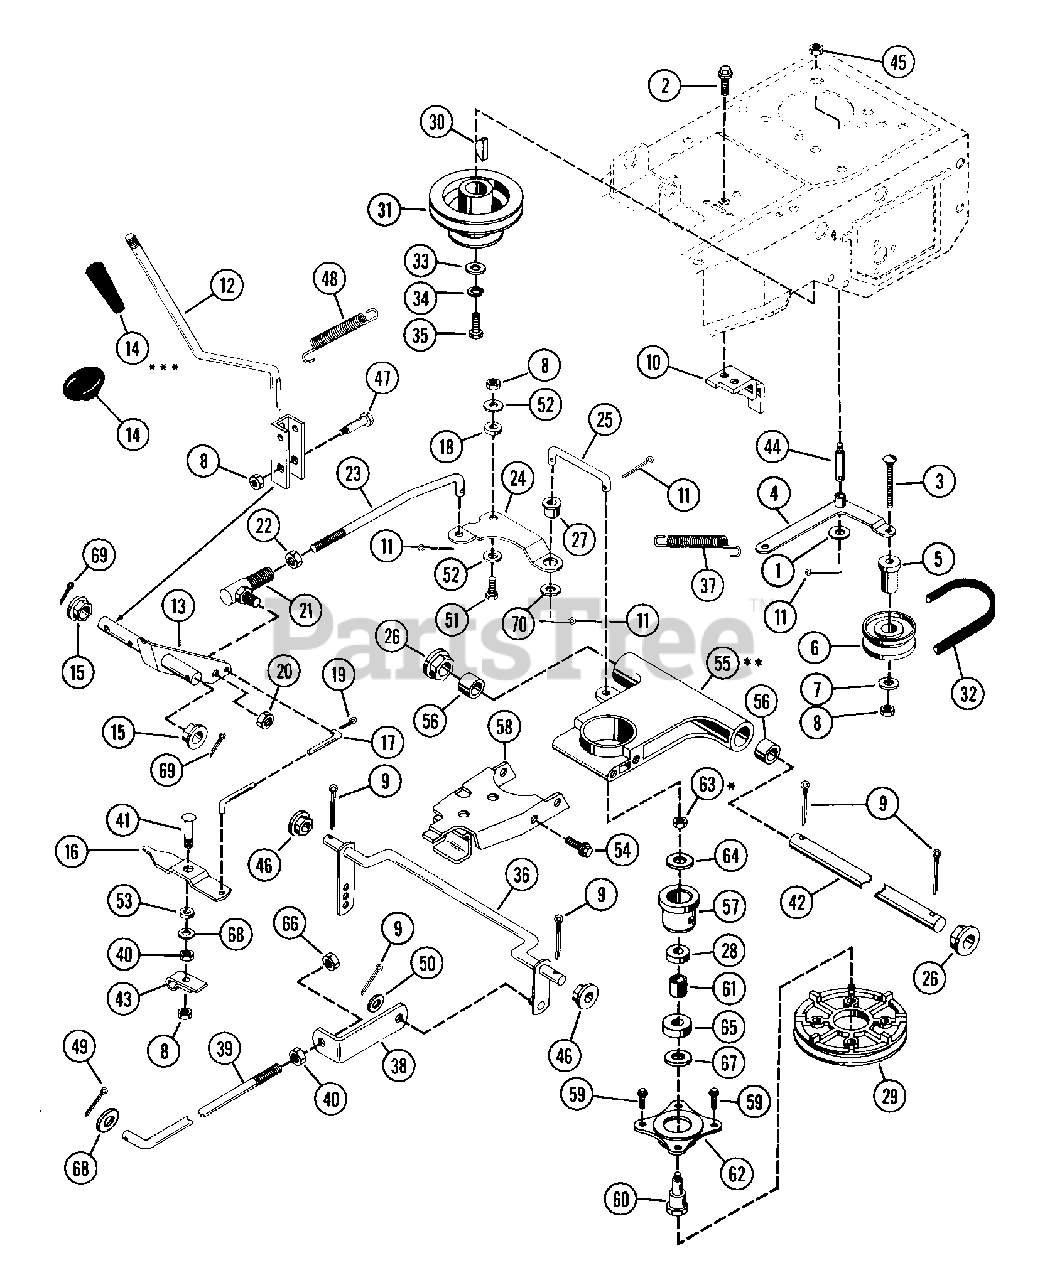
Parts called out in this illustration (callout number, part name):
1	WSHR-FL-STL .505X.880X.072 PL
2	BLT-SERHFWH .31-18X.50 PL
3	BLT-RDHDSQNK .31-18X1.25 SHTPL
4	IDLER ARM
5	SPACER -SHLD .344X.500X.469
6	IDLER
7	WSHR-FL-STL .38X.875X.083 PL
8	NUT-LK .312-18 GR A PL
9	PIN-COTR .12X1.0 PL
10	NEUTRAL STOP
11	PIN-COTR .09X.75 PL
12	SHIFT LEVER
13	SHIFT ARM
14	SHIFT BALL
14	GRIP
15	FLANGE BUSHING
16	INDICATOR
17	INDICATOR ROD
18	SPACER BUSHING .5 X .32 X .21
19	PIN-COTR .06X.50
20	NUT-LK-CTR .312-24 PL
21	SNAP IN BALL JOINT
22	NUT-HEX .312-24 PL
23	SHIFT ROD
24	BELL CRANK
25	SHIFT LINK
26	FLANGE BUSHING
27	BSHG-FLG .372X.500X.312X.625NY
28	BRG-BALL .625X1.375X.44
30	KEY-STR .25X2.0X.25
31	ENGINE SHEAVE
32	V-BELT, 3L-RAW EDGE
33	WSHR-FL-STL .505X1.140X.250
34	WSHR-LK .375X.115 HVY PL
35	BLT-HEX .38-24X1.25 BLKO GR5
36	CLUTCH SHAFT
37	SG-TENS .062X.72X6.65 WLD 7
38	CLUTCH BRACKET
39	ROD, CLUTCH
40	NUT-HEX .312-18
41	BLT-RDHDSQNK .31-18X1.0 SHT PL
42	TRANSFER SHAFT
44	SHOULDER STUD
45	NUT-LK-CTR .375-16 GR A PL
46	FLANGE BUSHING
47	SHOULDER BOLT .436 X .912
48	SG-TENS .092X.69X1.75 WLD 54
49	PIN-COTR .12X.75 PL
50	WSHR-FL-STL .520X.810X.033
51	BLT-HEX .31-18X.75 PL GR2
52	WSHR-FL-STL .344X1.125X.063PL
53	SPACER BUSHING .5 X .32 X .163
54	BLT-SCRHFWH .25-20X.62 PL
55	CARRIER ASSEMBLY
56	BSHG-SLV .625X.750X.500 BR
57	BEARING HOUSING
58	CARRIER YOKE
59	BLT-SERHFWH .31-18X.50 PL
60	SPINDLE BOLT
61	BSHG-SLV .634X1.000X.465
62	DISC ADAPTER
63	NUT-LK-CTR .50-20 PL
64	WSHR-HDND-STL-THR.515X.97X.062
65	BRG-BALL .750X1.781X.61
66	NUT-LK-NYL.312-18 PL
67	WSHR-HDND-THRST .758X1.23X.031
68	WSHR-FL-STL .323X.625X.062 PL
69	PIN-COTR .09X1.0 PL
70	WSHR-FL-STL .531X1.250X.100 PL
71	WSHR-FL-STL .380X.626X.033
